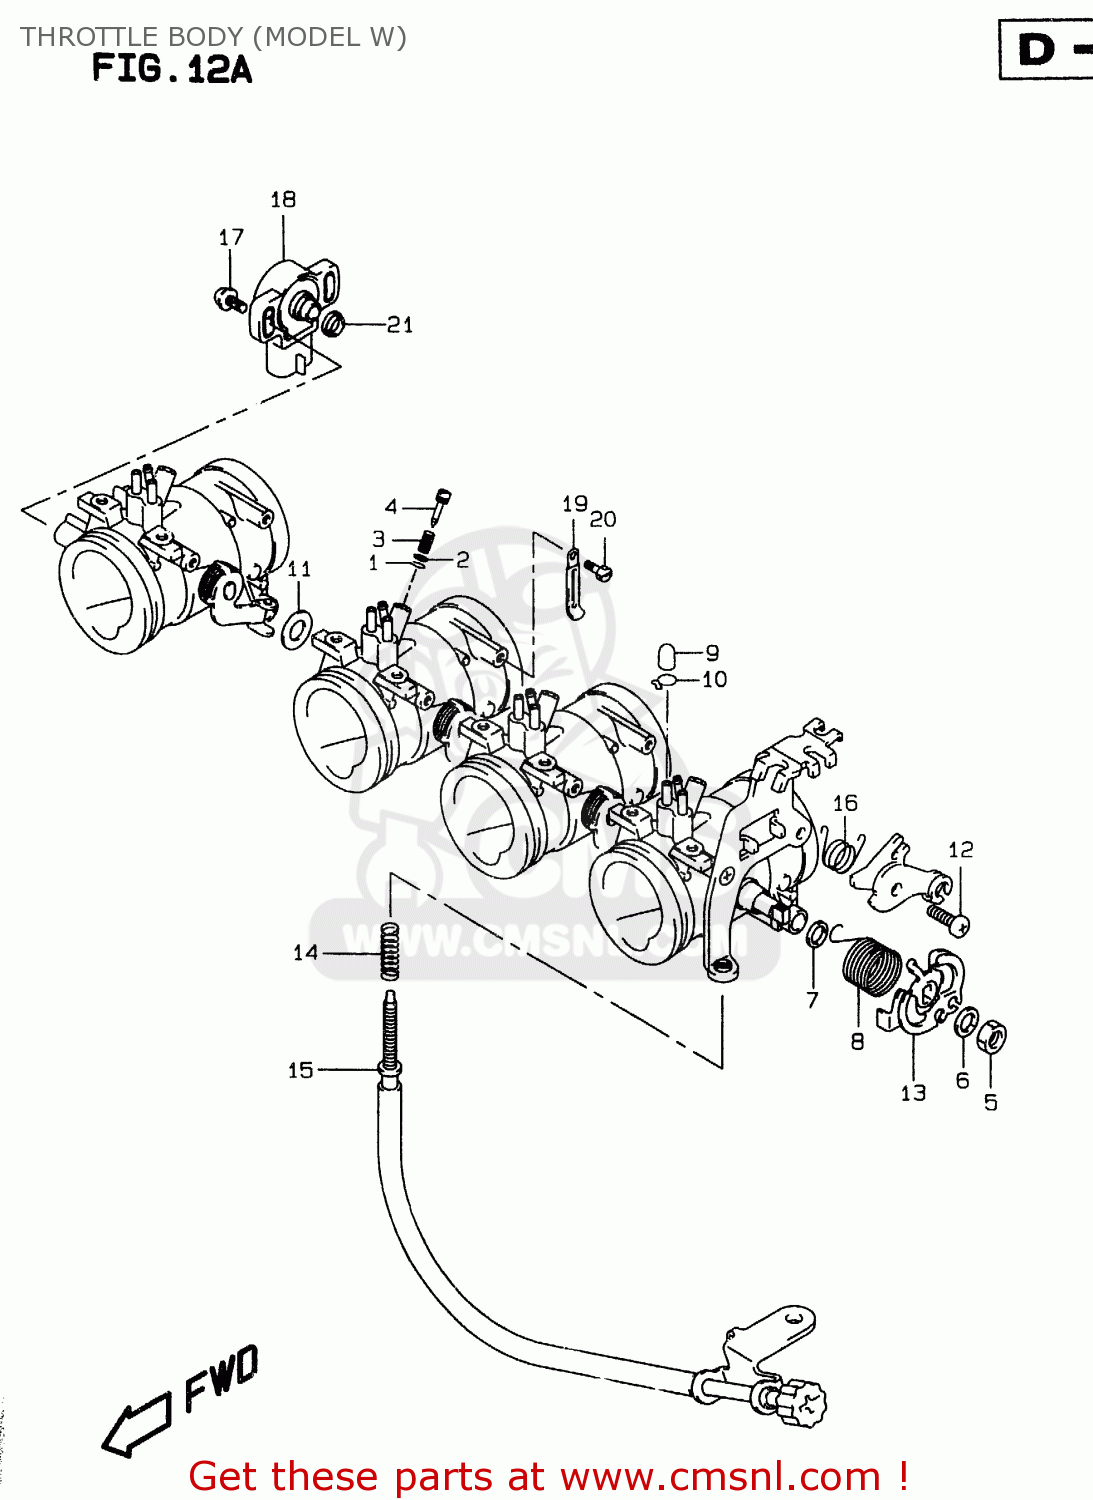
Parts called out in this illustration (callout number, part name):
1	O RING,PILOT AIR SCREW
2	WASHER
3	SPRING
4	SCREW
5	NUT
6	WASHER,LOCK
7	SEAL
8	SPRING
9	CAP
10	CLIP
11	GASKET,THROTTLE SHAFT (NAS)
12	SCREW,STARTER LEVER
13	WASHER
14	SPRING
15	ADJUSTER
16	SPRING
17	SCREW
18	SENSOR ASSY,THROTTLE
19	CLAMP(L:45)
20	BOLT
21	GASKET,THRO VALVE INSPECTION (NAS)
